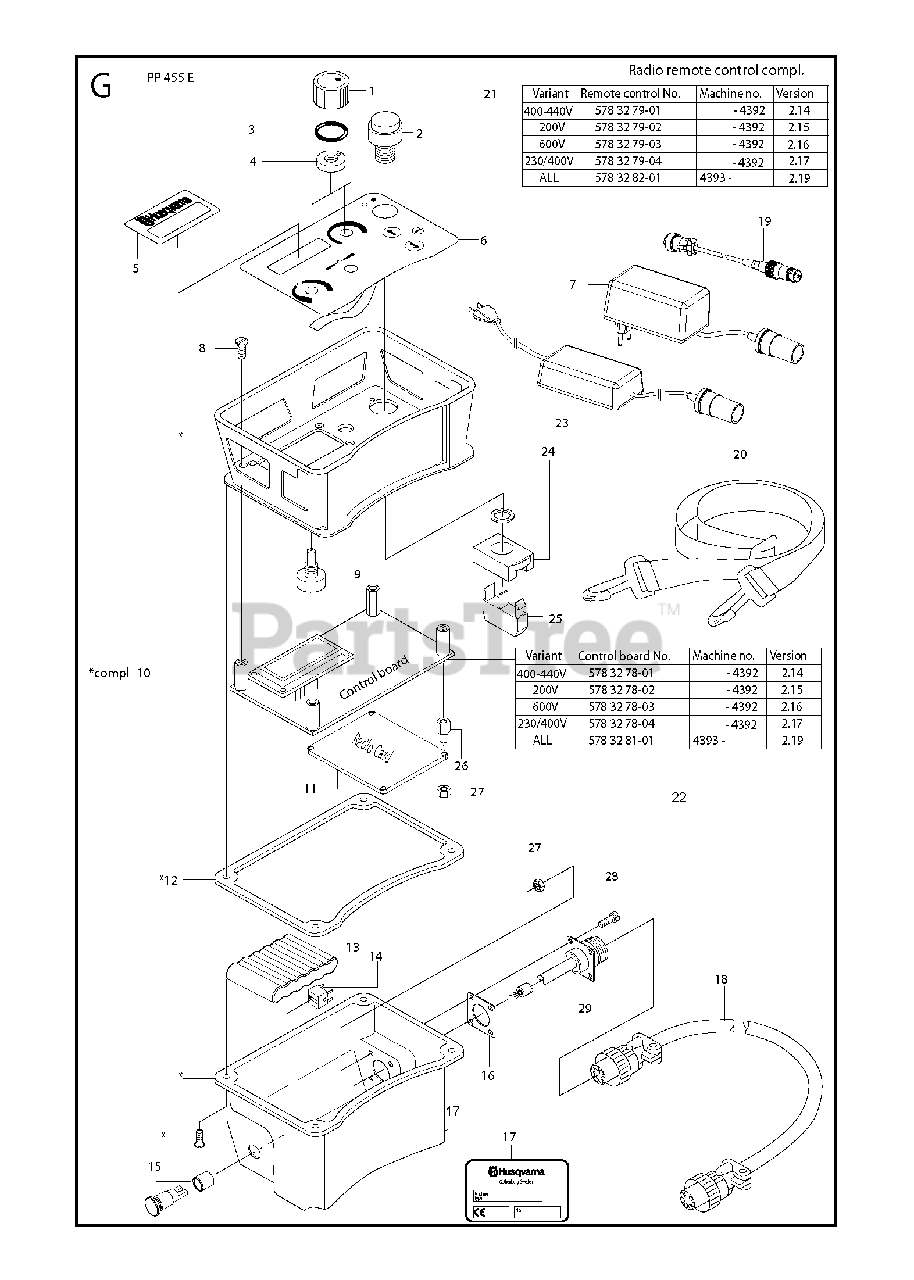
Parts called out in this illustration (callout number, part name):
21	REMOTE CONTROLVariant 400-400V, Machine no. -4392, Version 2.14
21	REMOTE CONTROLVariant 200V, Machine no. -4392, Version 2.15
21	REMOTE CONTROLVariant 600V, Machine no. -4392, Version 2.16
21	REMOTE CONTROLVariant 230/400V, Machine no. -4392, Version 2.17
21	REMOTE CONTROLVariant ALL, Machine no. 4393-, Version 2.19
22	PRINTED CIRCUIT ASSYVariant 400-400V, Machine no. -4392, Version 2.14
22	PRINTED CIRCUIT ASSYVariant 200V, Machine no. -4392, Version 2.15
22	PRINTED CIRCUIT ASSYVariant 600V, Machine no. -4392, Version 2.16
22	PRINTED CIRCUIT ASSYVariant 230/400V, Machine no. -4392, Version 2.17
22	PRINTED CIRCUIT ASSYVariant ALL, Machine no. 4393-, Version 2.19
